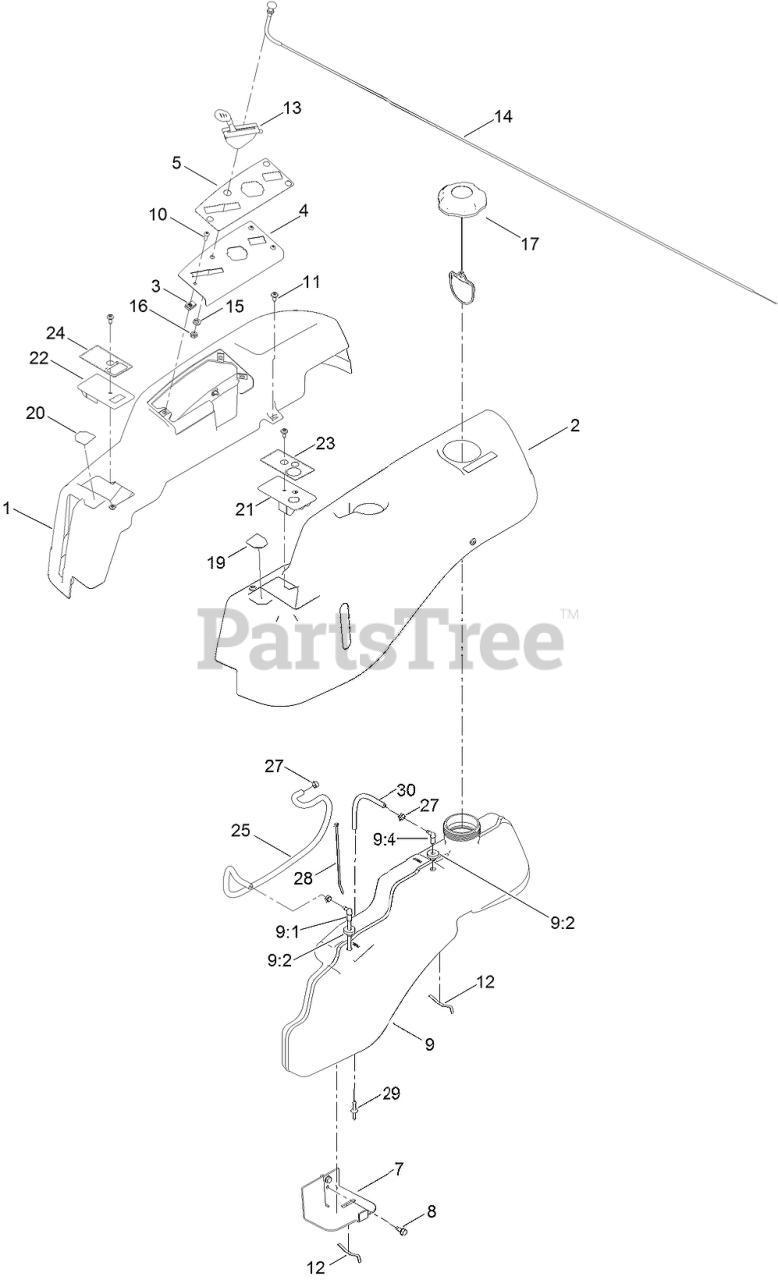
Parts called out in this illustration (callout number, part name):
1	POD-RH
2	POD-LH
4	PLATE-CONTROL
5	DECAL-PANEL, CONTROL
7	SUPPORT-TANK, FRONT
8	SCREW-HWHTF
9	FUEL TANK ASM
9:1	CONNECTOR-ELBOW, 90 DEG
9:2	BUSHING
9:4	FITTING-PLASTIC
10	SCREW-PRH
11	SCREW-SHOULDER
12	SPRING
13	CABLE-THROTTLE
14	CABLE-CHOKE
15	WASHER-LOCK
16	NUT-HJ
17	CAP-FUEL, RATCHETING
19	DECAL-NMIR
20	DECAL-CONTROL, PEDAL
21	COVER-LH
22	COVER-RH
23	DECAL-KEYCHOICE
24	DECAL-BRAKE, PARKING
25	HOSE-FUEL
27	CLAMP-HOSE
29	ADAPTOR-ORIFICE
30	HOSE-FUEL
